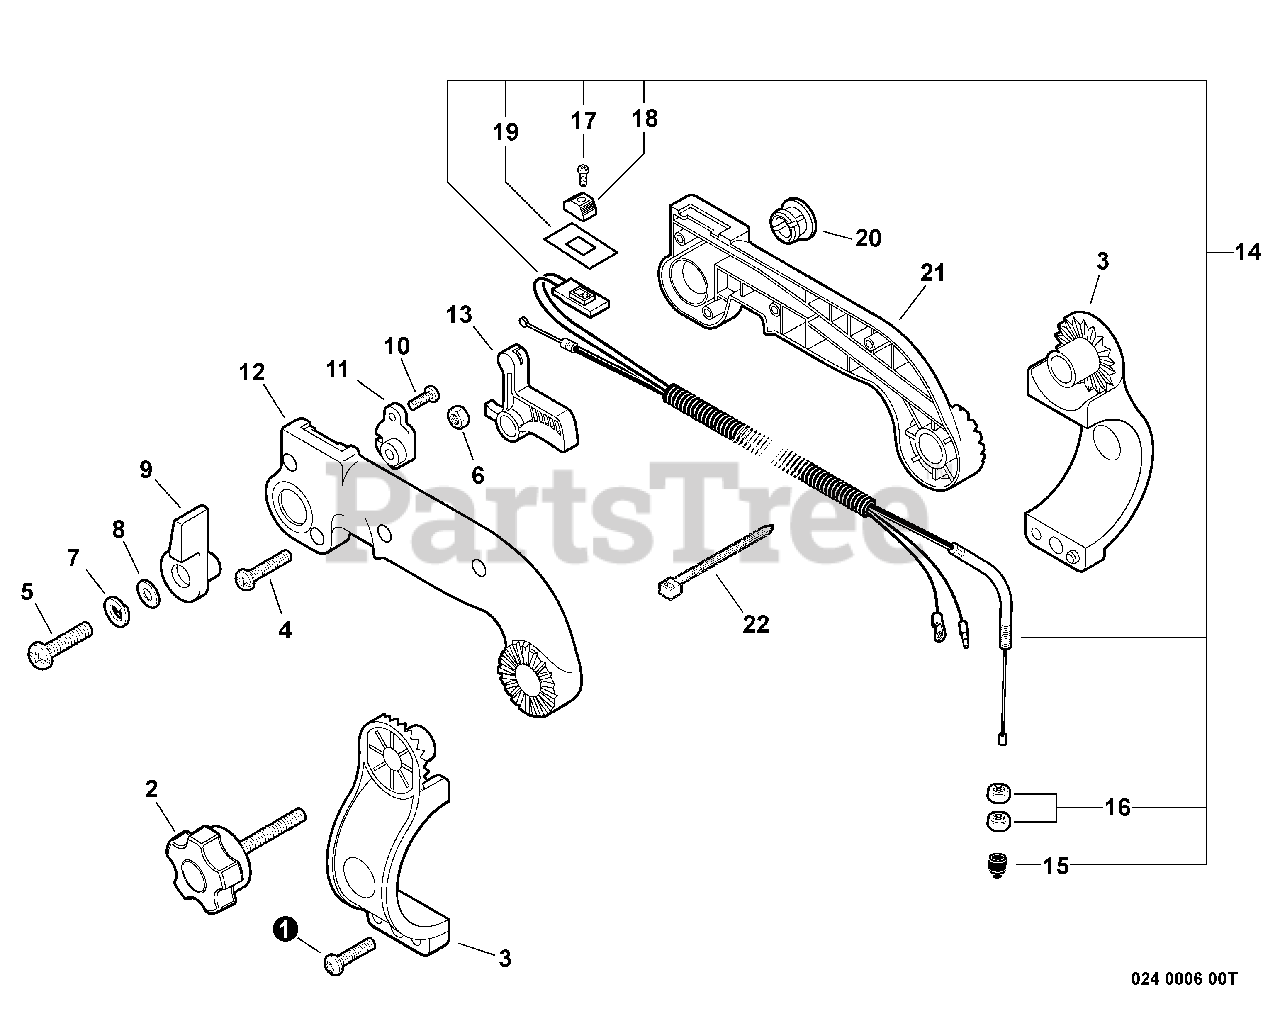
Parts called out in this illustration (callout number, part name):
1	SCREW - 5X20 -- TAPPING
2	THUMBSCREW
3	HANDLE BRACKET KIT
4	SCREW - 4X22
5	SCREW - 6X20
6	LOCKNUT - 6
7	LOCKWASHER - 6
8	WASHER - 6
9	CONTROL, THROTTLE
10	SCREW - 4X10
11	BRACKET, THROTTLE
12	HANDLE, CONTROL - LEFT
13	TRIGGER, THROTTLE
14	CONTROL CABLE ASSY
15	CAP, DUST
17	SCREW - 3X10
18	KNOB, SWITCH - ORANGE
19	COVER, SWITCH - STOP
21	HANDLE, CONTROL - RIGHT
22	TIE, CABLE - SMALL
